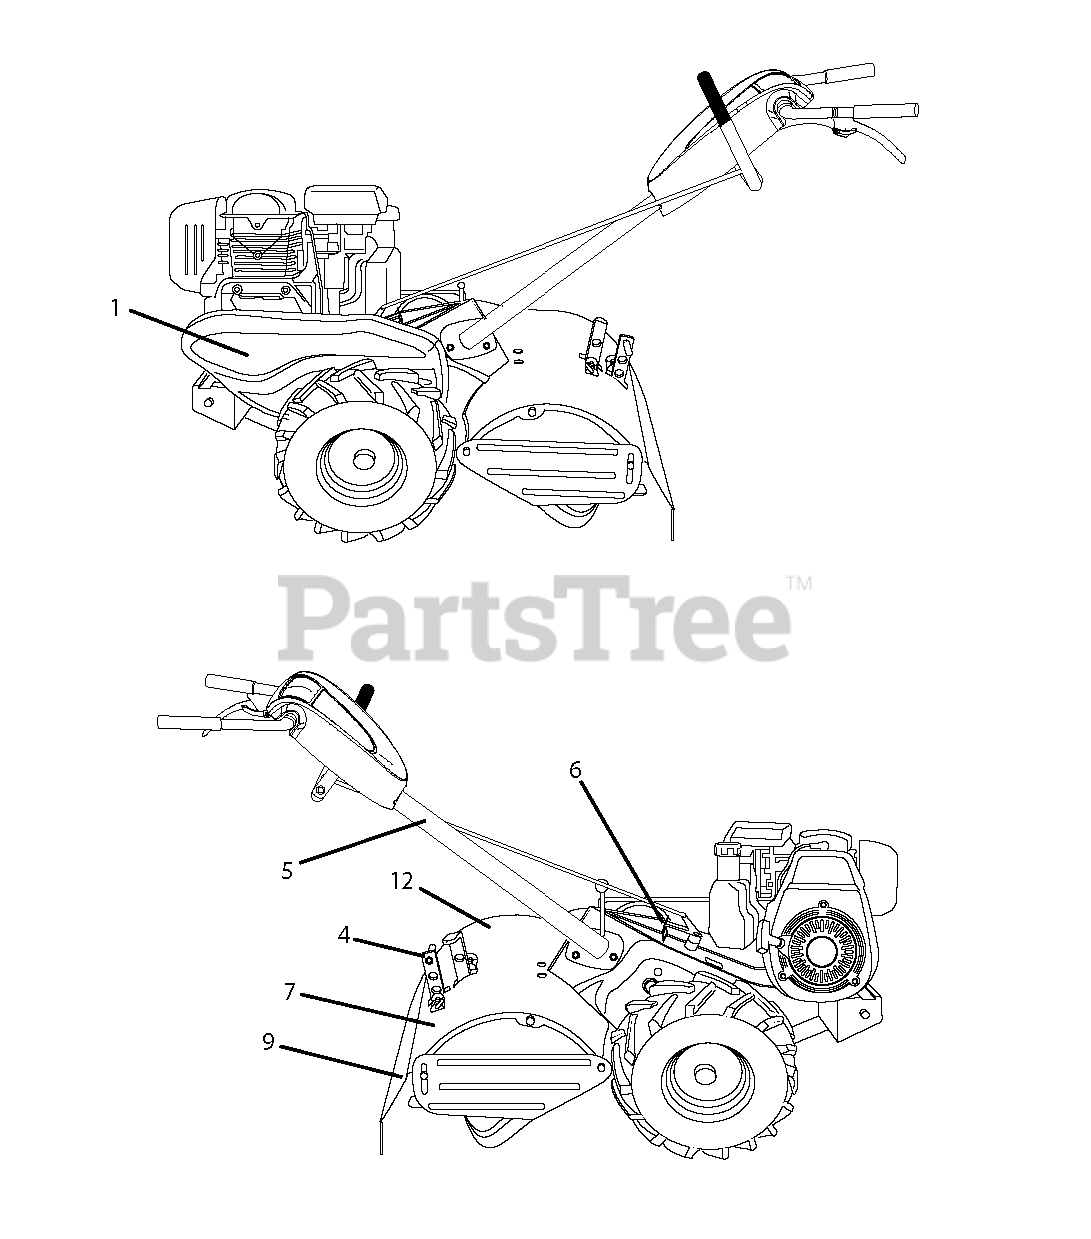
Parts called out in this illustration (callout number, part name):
1	RP.DECAL.BADGE.170MM.TEXTLOGO
4	DECAL.SHIELD.TN.DRT17.HUSQ
5	DECAL TI (2 2)
6	DECAL.SHIFT.INDICATOR.DRT
7	DECAL.REVERSE.HUSQ.TILLER
9	DECAL.DRT.WARN.ENG/F
12	DECAL.FOWARD.HUSQ.TILLER
